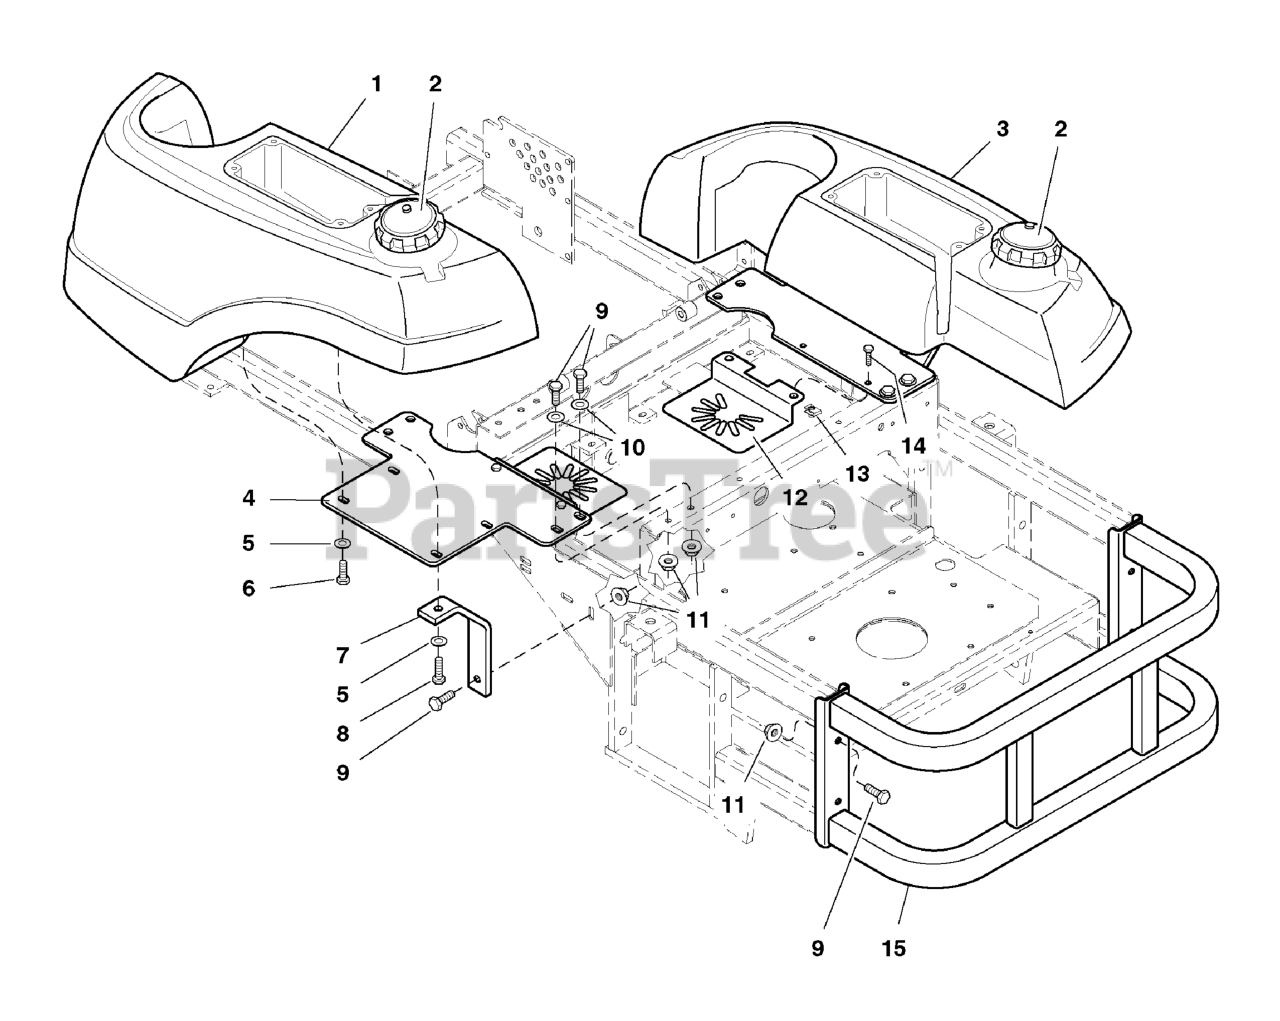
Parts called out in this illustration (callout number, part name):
1	FUEL TANK, IS3000Z, LH
1	Filler Neck
2	CAP, FUEL TANK, 3-1/2 NECK
3	FUEL TANK, IS3000Z, RH
3	Filler Neck
4	FUEL TANK MOUNT
5	WASHER, 5/16" SAE
6	BOLT, 5/16-18 X 3/4 GD5
7	TANK MOUNT SUPPORT
8	BOLT, 5/16-18 X 1 GD5 YZ
9	BOLT, 3/8-16 X 1" GD5 CZ
10	WASHER, 3/8 SAE
11	NUT, 3/8-16 Hex Serrated Flange
12	FAN SHIELD
13	BODY CLIP, 1/4-20
14	BOLT, 1/4-20 x 3/4
